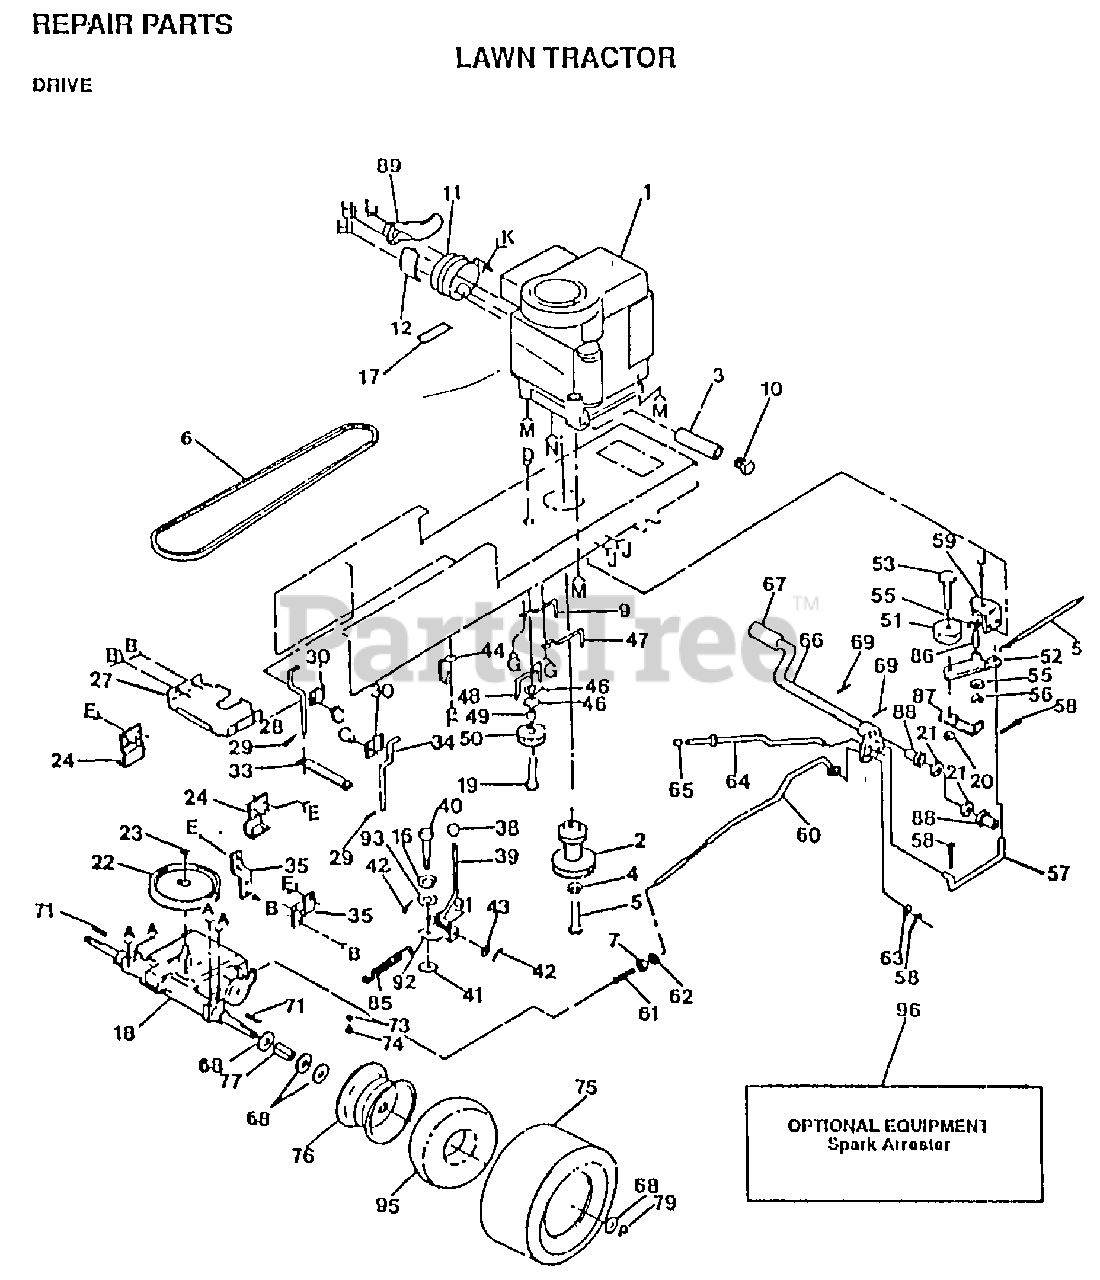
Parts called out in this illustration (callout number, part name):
3	"PIPE, DRAIN OIL"
4	LOCKWASHER
6	BELT-V.90.0.GD.DR
7	NUT
9	KEEPER BELT ENGLH
10	PLUG, DRAIN, OIL
11	MUFFLER LTV
12	SHIELD HEAT LTV
16	LOCKWASHER
19	BOLT
21	WASHER LT
22	PULLEY TRANS
24	BRACKET LT
27	BRKT SUPPORT LT
28	KEEPER BELT LH
29	SPRING.RETAINER
30	CLAMP LT
33	STRAP LOCATOR
34	KEEPER BELTRH
35	STRAP TORQUE
38	CONTROL KNOB LT
39	ROD SHIFTER
41	WASH-SHFT PLT LT
42	PIN COTTER 1/8
43	WASHER
46	WASHER
47	"KEEPER,BLT ENG LT"
48	BELT KEEPER LT
49	SPACER T
50	PULLEY.IDLER.FLAT
52	ARM IDLER
55	WASHER LT
56	KLIP RING
57	"LINK, CLUTCH T"
58	COTTER PIN
59	BRKT ASM
60	BRAKE ROD LT
61	SPRING ROD LT
62	NUT
63	WASHER
67	PEDAL COVER T
68	WASHER
71	SQUARE KEY
73	VALVE CAP
74	VALVE STEM LT
77	SPACER LT
79	E-RING LT
86	"LY, BEARING"
87	RETAIN BELT
88	NYLON BEARING
89	DEFLECTOR MUFFLER
91	SPRING LT
92	PLATE SHIFT LT
93	WASHER LT
95	TUBE.18X9.5-8
